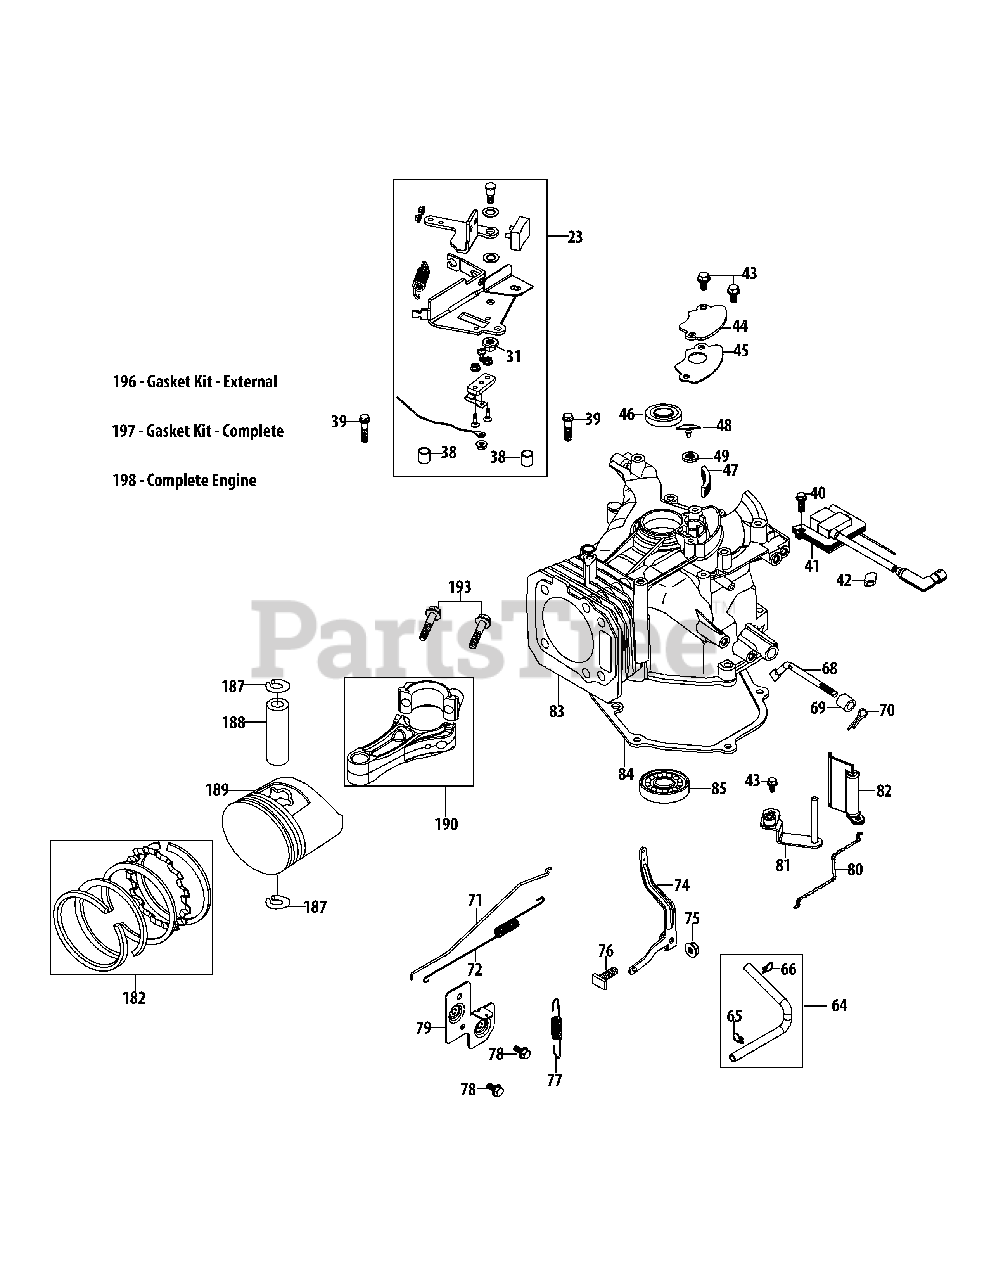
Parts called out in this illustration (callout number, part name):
23	Brake Assembly
30	Brake Arm Nut
38	Brake Spacer
39	Bolt M6X35
40	Bolt M6X30
41	Ignition Coil Assembly
42	Ignition Coil Spacer
43	Bolt M6X14 Multi-Purpose
44	Breather Cover Plate
45	Breather Gasket
46	Upper Crankshaft Seal
47	Breather Screen
48	Breather Valve
49	Breather Valve Base
64	Breather Hose Assembly
65	Breather Hose Clamp
66	Breather Hose Clamp
68	Governor Arm Shaft
69	Governor Seal
70	Governor Arm Shaft Cotter Pin
71	Throttle Linkage
72	Throttle Linkage Spring
74	Governor Arm
75	Governor Arm Nut M6
76	Governor Arm Bolt
77	Governor Spring
78	Bolt M6X12
79	Component Bracket
80	Choke Linkage
81	Air Vane Bracket
82	Air Vane
83	Short Block
84	Crankcase Cover Gasket
85	Main Bearing
182	Piston Ring Set
187	Piston Pin Snap Ring
188	Piston Pin
190	Connecting Rod Assembly
193	Connecting Rod Bolt
194	Oil Drain Plug And Washer Ass'y
196	Gasket Kit - External
197	Gasket Kit - Complete
198	Complete Engine
